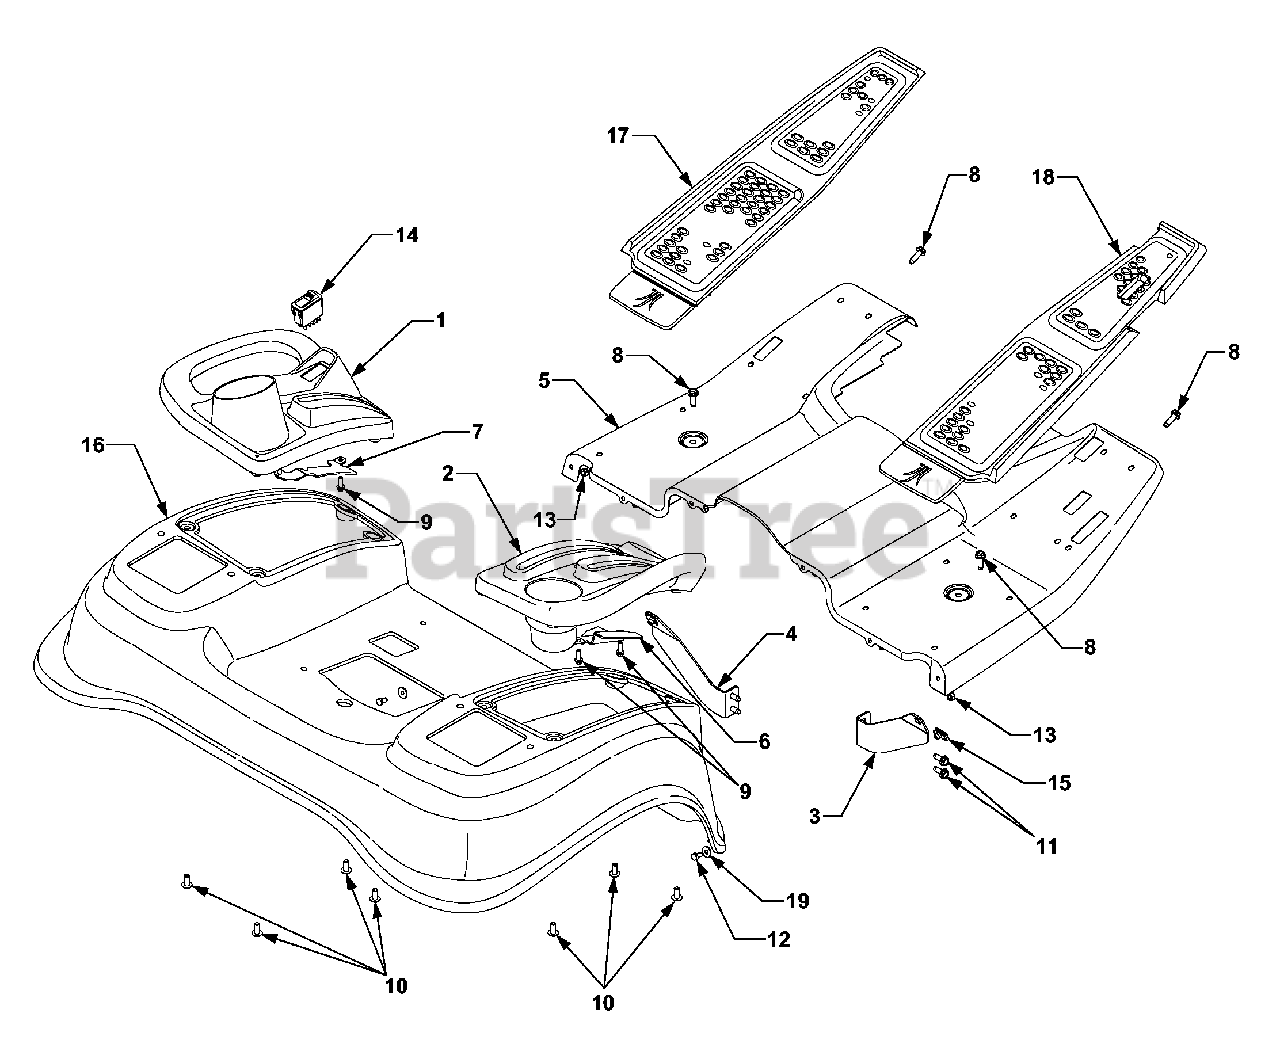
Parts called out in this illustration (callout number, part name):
1	Cover, Fender, LH
2	Cover, Fender, RH
3	Bracket, Running Board Mtg. RH
4	Bracket, Running Board Mtg. LH
5	Running Board
9	Screw, Hex Wash. Hd, Tapp 1/4-15 x .75
10	Screw, Truss Phillips Hd. 5/16-14 x .75
11	Screw, Hex Wash. Hd. Tapp 5/16-18 x .75
12	Screw, Hex Cap, 1/4-20 x .5 GR5
13	Nut, Hex Insert Lock, 1/4-20 GR8
14	Switch, PTO Reverse
15	Nut, Speed, 5/16-18
16	Fender
17	Pad, Floor - LH
18	Pad, Floor - RH
19	Washer, Flat, .26 x .72 x .06
